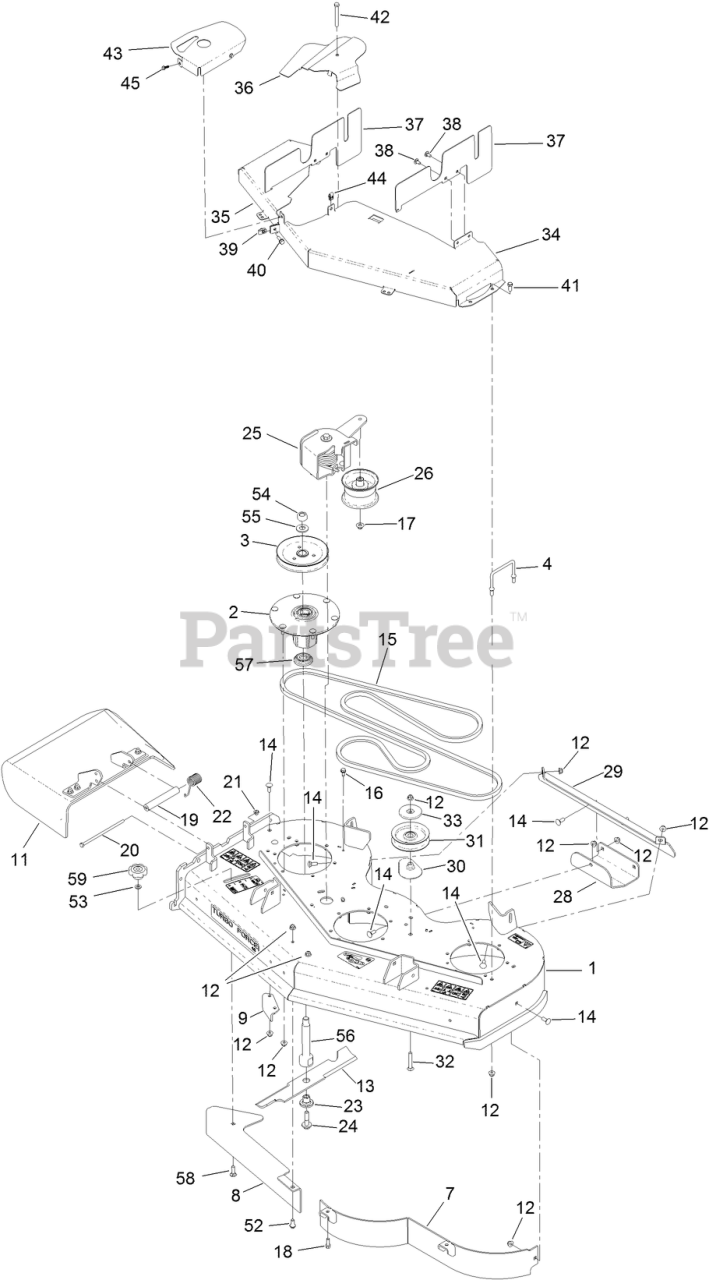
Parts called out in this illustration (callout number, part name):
1	48 DECK ASM
2	SPINDLE ASM
3	SHEAVE-BLADE, DRIVE
4	WIREFORM-COVER
7	48 INCH BAFFLE ASM
8	PLATE-BAFFLE, FORMED [RED]
9	BAFFLE-DISCHARGE
11	DEFLECTOR ASM
12	NUT-HF, NI
13	BLADE-16.50 HIGH FLOW
14	BOLT-CARR
15	BELT-V
16	SCREW-HWHTF
17	NUT-FLANGE, NI
19	SPACER
20	SCREW-HH
21	NUT-HF, NI
22	SPRING-TORSION
23	BUSHING-HEX
24	SCREW-SEMS
25	GS TORSION IDLER ASM II
26	PULLEY-IDLER
29	BRACKET-SKID
30	SPACER-PULLEY
31	PULLEY-IDLER, FLAT
32	SCREW-CARR
33	SHIELD-DUST
34	COVER-BELT, LH, CE
35	COVER-BELT, RH CE
36	COVER-IDLER, CE
37	COVER-SIDE, LH (CE)
38	SCREW-CARR
39	NUT-U
40	SCREW-HHF
41	SCREW-HH
42	SCREW-HH
43	COVER-IDLER, CE
45	SCREW-HHF
52	BOLT-SHOULDER
53	WASHER-HARDENED
54	NUT-HEX
55	WASHER
56	SHAFT-SPINDLE
57	GUARD-BOTTOM
58	BOLT-CARR
